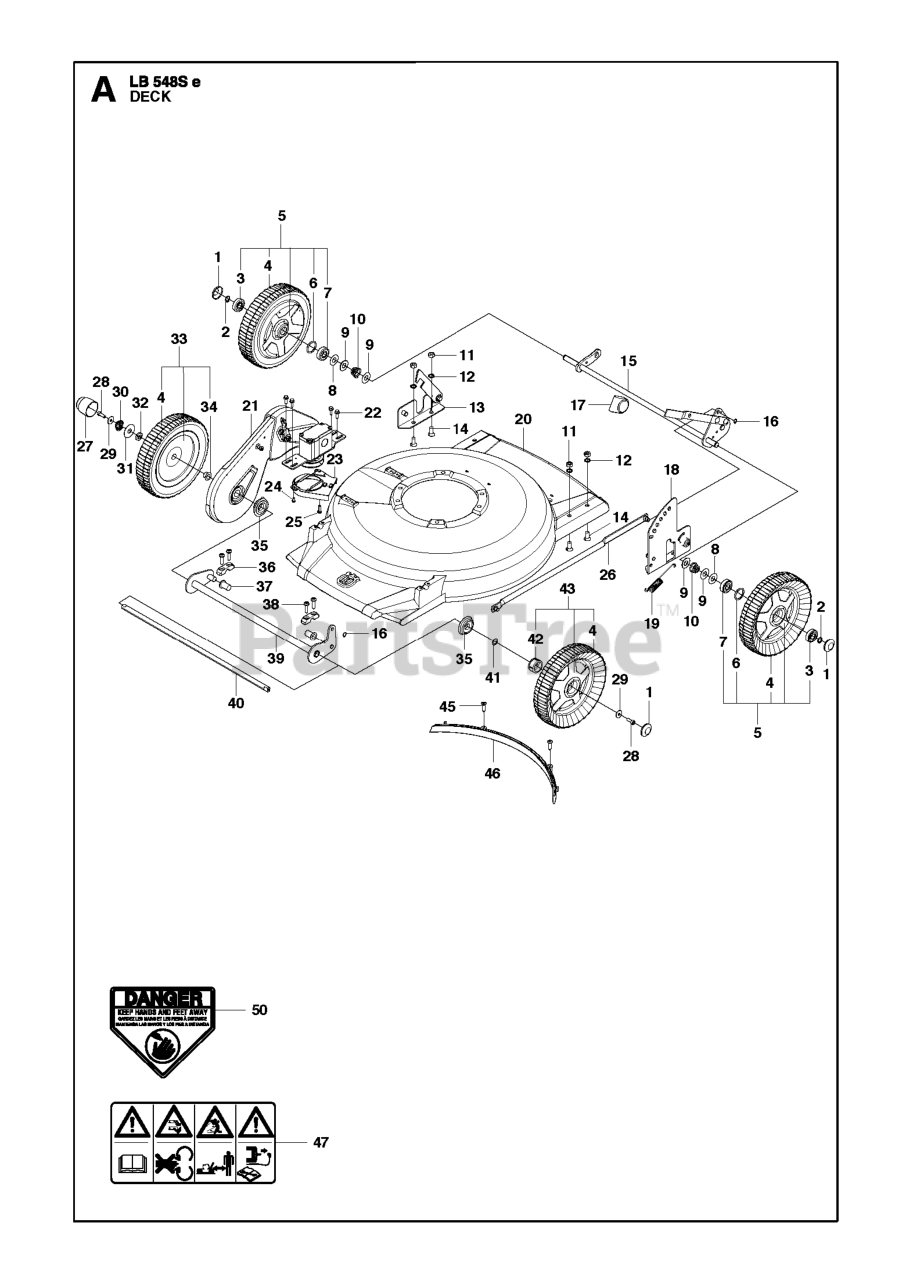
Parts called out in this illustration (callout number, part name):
11	NUT
16	RETAINING RING SGA 8
50	LABEL, DANGER
